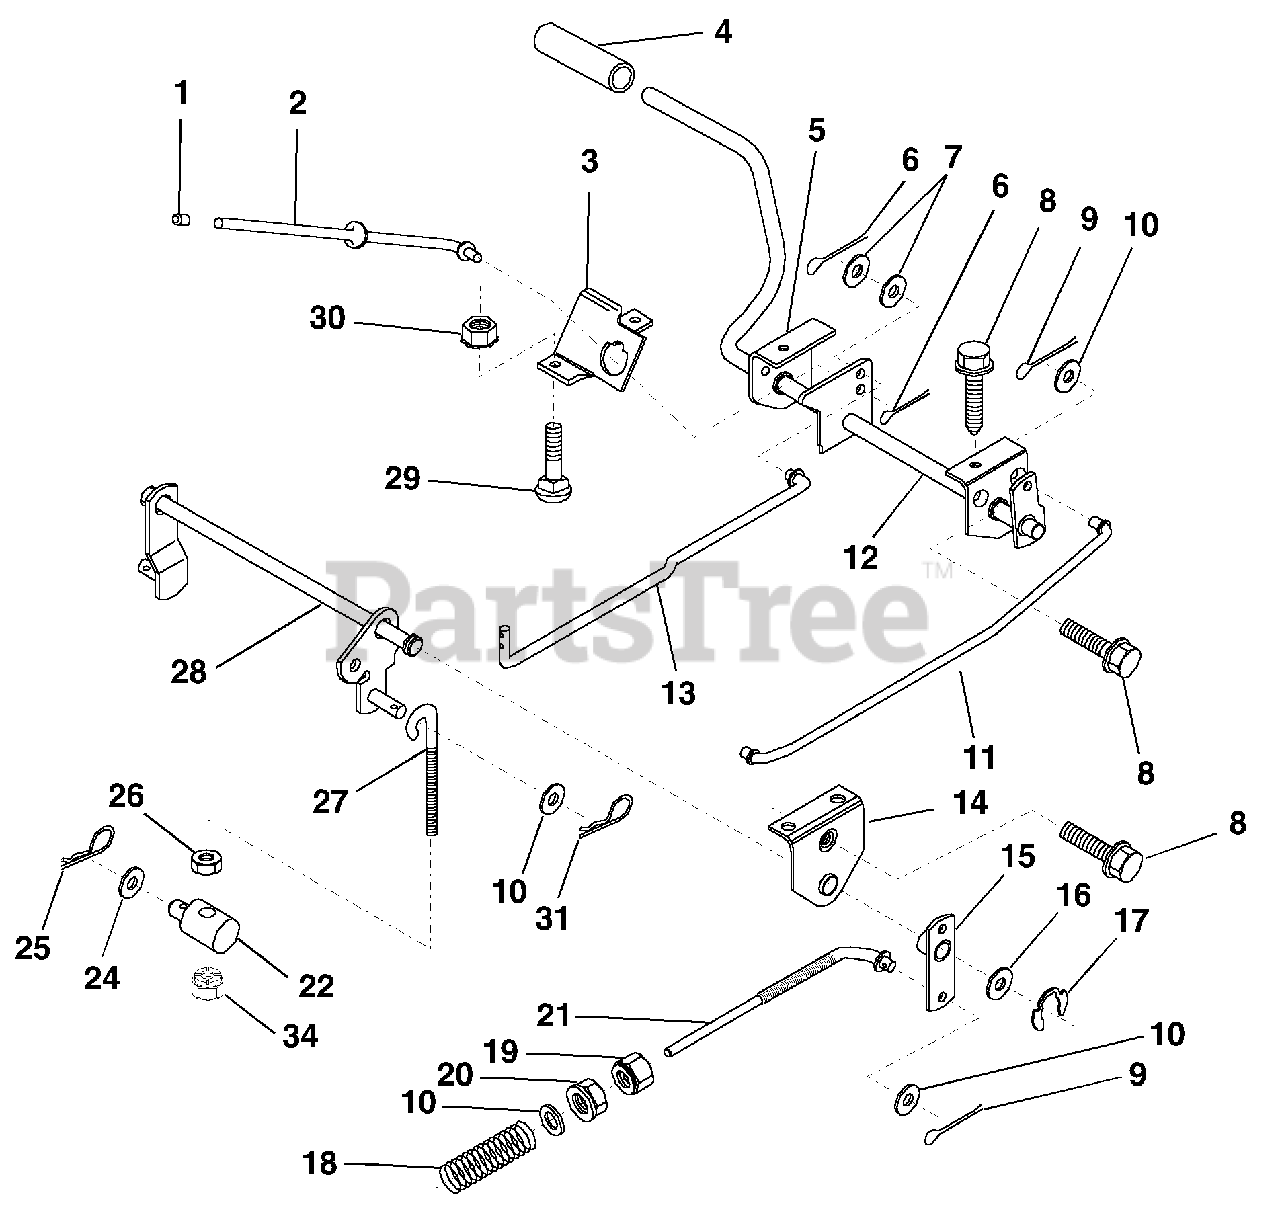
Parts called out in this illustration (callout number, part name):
1	Cap, Plunger
2	Rod, Parking Brake
3	Bracket, Parking Brake
4	Cover, Pedal
5	Bracket, Clutch/Brake Pedal, L.H.
6	Pin, Cotter 3/32 x 3/4
7	Washer 13/32 x 5/8 x 16 Ga.
8	Screw, Hex, Thd. Roll. 5/16-18 x 1/2
9	Pin, Cotter 1/8 x 3/4
10	Washer 13/32 x 13/16 x 16 Ga.
11	Rod, Brake Front
12	Assembly, Clutch/Brake Pedal
13	Rod, Clutch
14	Bracket, Lift, Shaft
15	Assembly, Brake, Pivot, Arm
16	Washer 25/32 x 1-1/8 x 16 Ga.
17	Ring, Klip
18	Spring, Brake Rod
19	Nut, Hex, Jam 3/8-16 UNC
20	Nut, Lock, hex. w/Ins. 3/8-16 INC
21	Rod, Rear Brake
22	Trunnion, Lift
24	Washer 13/32 x 1-1/4 x 12 Ga.
25	Spring, Retainer
26	Nut, Centerlock 3/8-16 UNC
27	Link, Threaded
28	Assembly, Rear Mower Lift
29	Bolt, Carriage 5/16-18 UNC x 3/4
30	Nut, Keps 5/16-16 UNC
31	Retainer Spring
34	Nut, Crownlock 3/8-16 UNC
